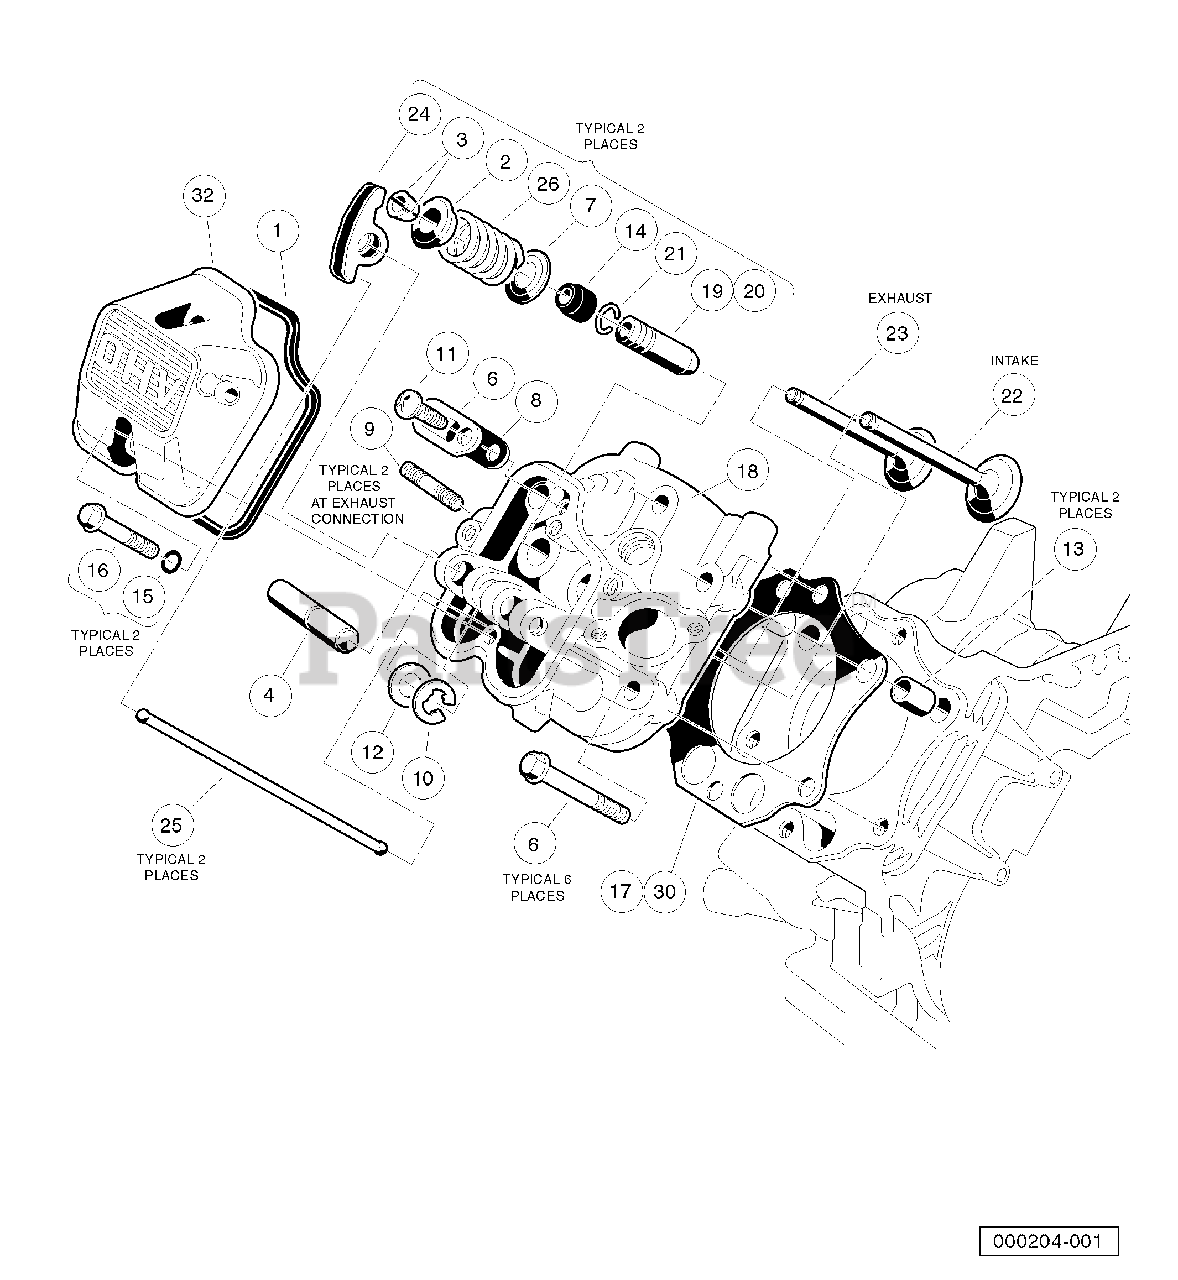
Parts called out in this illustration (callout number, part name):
1	Gasket, Rocker Case
2	Retainer, Valve Spring
4	Shaft, Rocker
5	Bolt, Flange Head, M8 x 1.25 x 45 mm
7	Seat, Spring
9	Stud, Two-Ended, M8-1.25
10	Circlip, Type-E
12	Washer, 12.1x19x1.8
16	Bolt, 6x35
17	Gasket, Head
18	Assembly, Cylinder Head, FE350
19	Guide, Valve, Exhaust
20	Guide, Valve, Intake
22	Valve, Intake
23	Valve, Exhaust
24	Arm, Rocker
26	Spring, Engine Valve
27	Kit, Gasket, FE350
28	Gasket, Engine to Insulator
29	Gasket, Exhaust
30	Gasket, Head
31	Gasket, Crankcase Cover
32	Case, Rocker -w/o Logo Fe290
